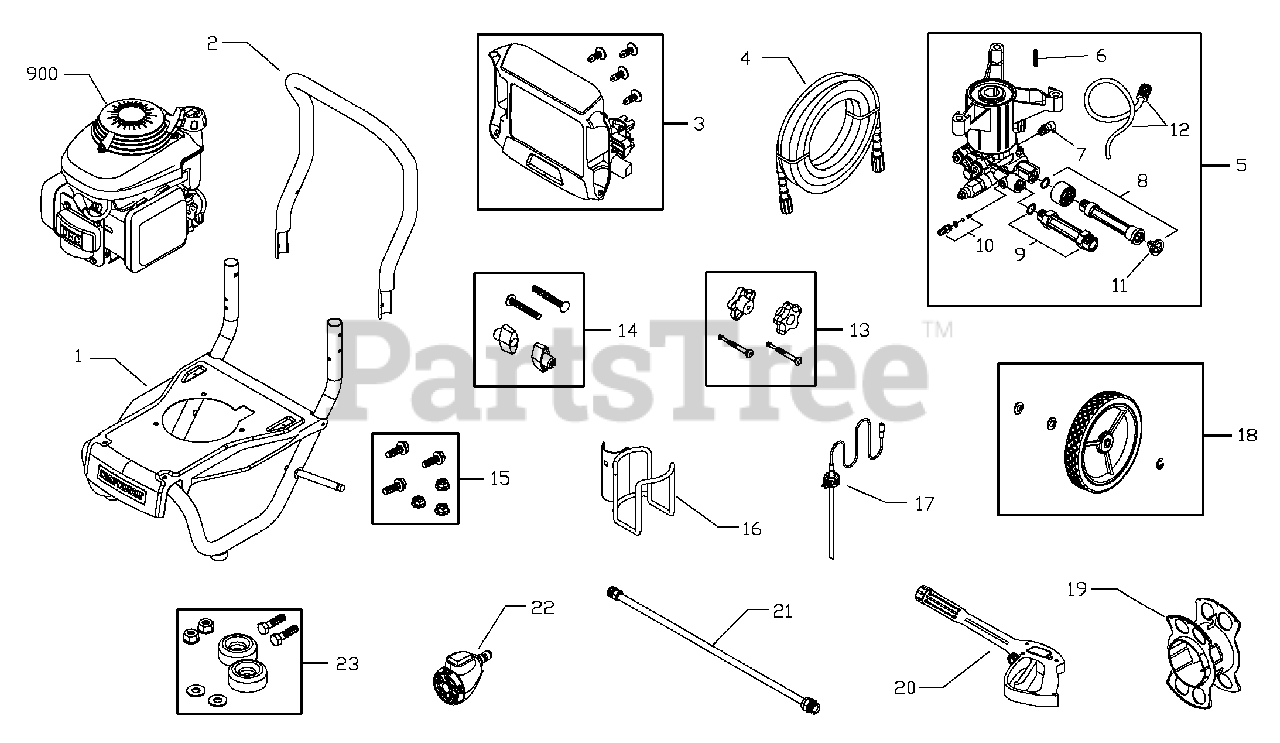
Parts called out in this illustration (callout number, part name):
2	HANDLE
4	HOSE
5	PUMP
7	VALVE, Thermal Relief
8	KIT, Water Inlet
10	KIT, Chemical Injection
11	FILTER, Garden Hose
12	KIT, Chemical Hose
15	KIT, Hardware Pump Mounting
20	GUN
21	EXTENSION, QC
22	NOZZLE, QC
23	KIT, Vibration Mount
900	*ENGINE
